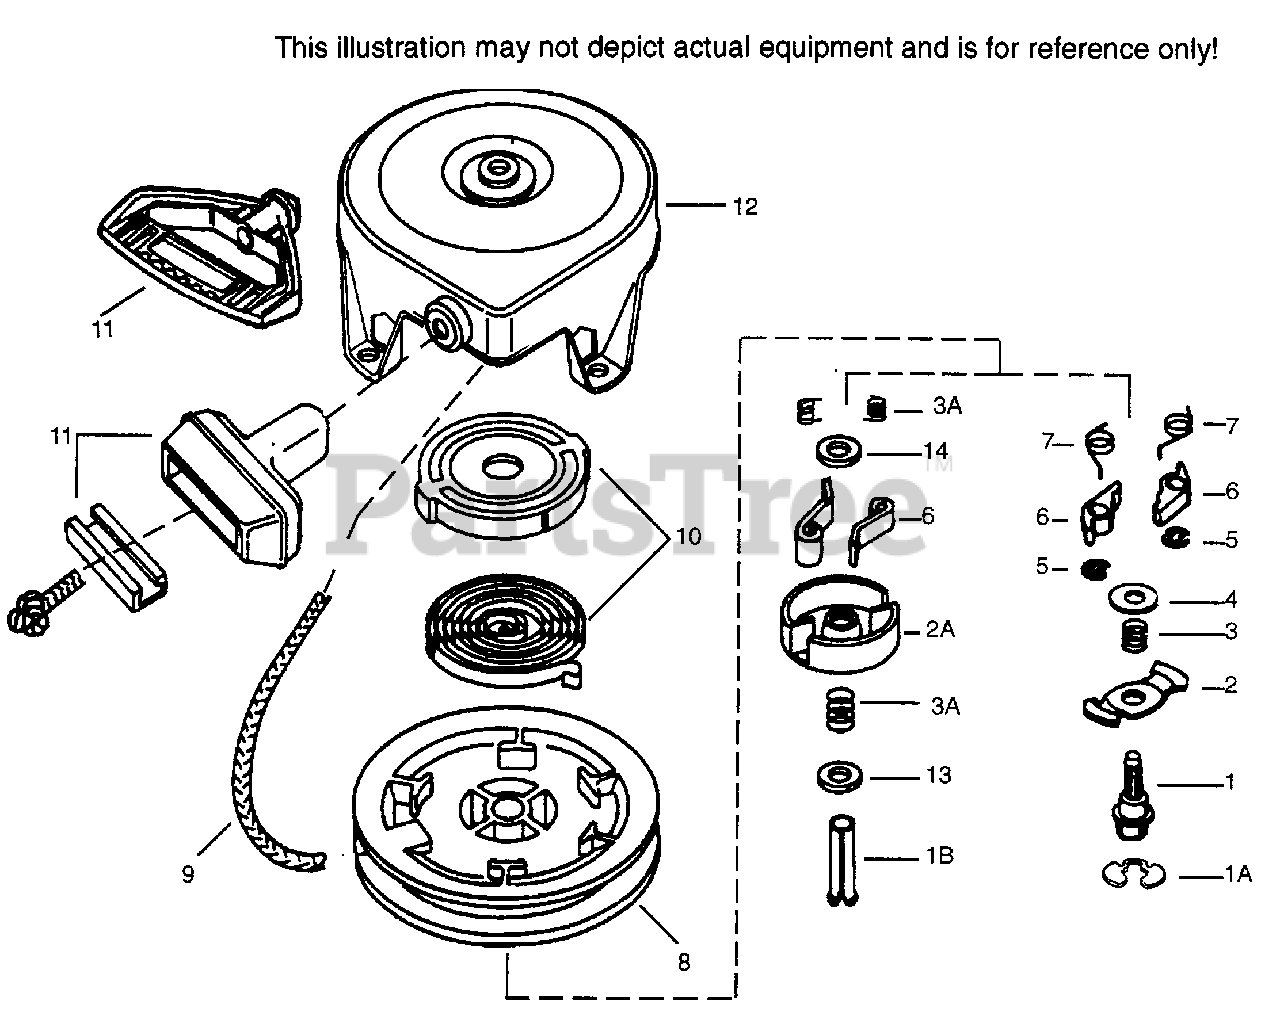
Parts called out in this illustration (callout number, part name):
1A	Retaining Ring
2	Dog Cam
3	Brake Spring
5	Retaining Ring
6	Starter Dog
7	Dog Spring
8	Pulley
9	Starter Rope
10	Spring & Keeper Ass'y.
11	Starter Handle (Mitten Grip) (also av ailable in Packaged Part #740053B) ar ter)
12	Starter Housing Ass'y.
